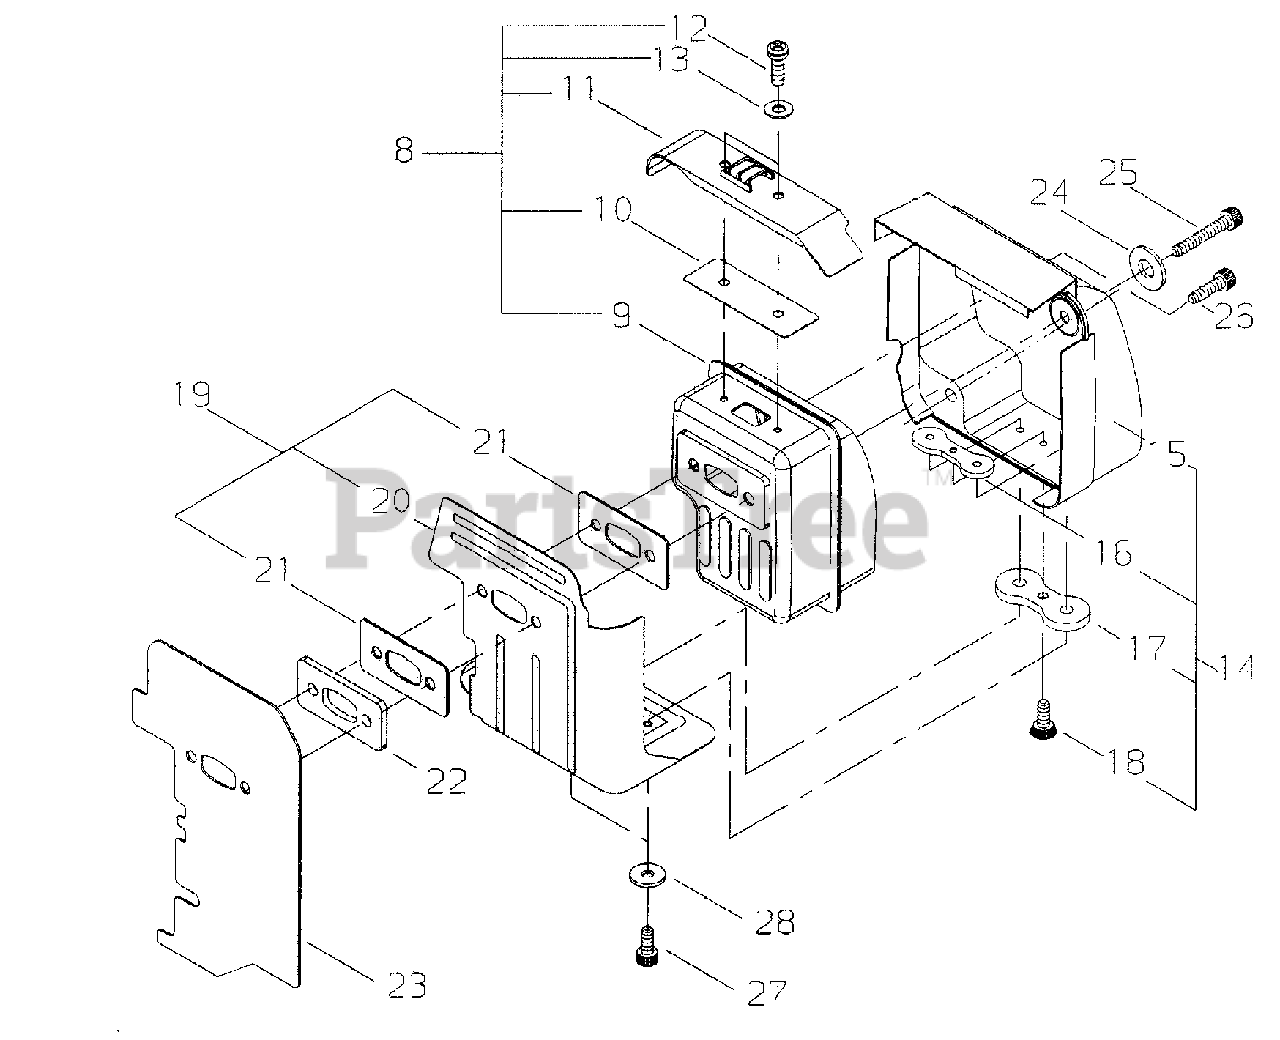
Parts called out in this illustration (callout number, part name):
8	MUFFLER ASSY
9	MUFFLER
10	SCREEN, SPARK ARRESTER
11	COVER, SPARK ARRESTER
12	SCREW M4×6
13	WASHER 4 MM
14	COVER ASSY, MUFFLER
15	COVER, MUFFLER
16	PLATE
18	SCREW 4×8
19	DEFLECTOR ASSY, EXHAUST HEAT
20	HEAT SHIELD, EXHAUST
21	GASKET, EXHAUST
22	SPACER
23	GASKET, MUFFLER
24	WASHER SS 5 MM
25	BOLT M5×65
26	BOLT 5×25
27	BOLT M5×10
28	WASHER Ø15ר5.2×1.6
